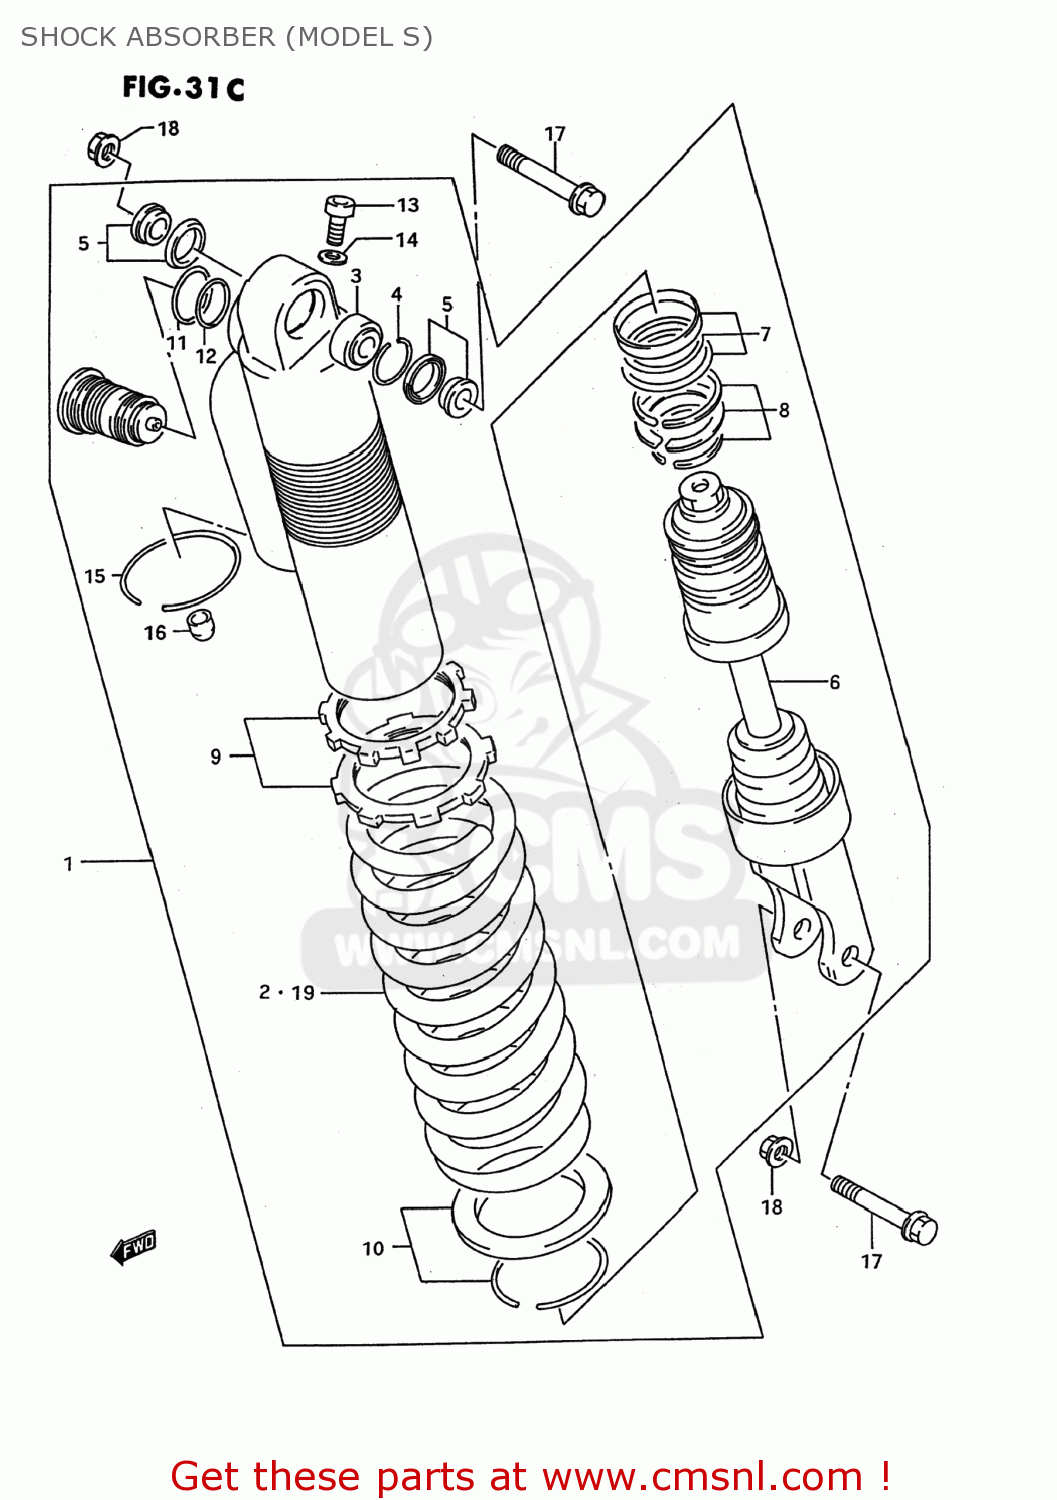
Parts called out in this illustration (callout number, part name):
1	ABSORBER ASSEMBLY,REAR SHOCK
2	SPRING
3	BEARING,RR CUSHION LEVER RR
4	RING,STOPPER
5	COLLAR SET,RR SHOCK ABSORBER
6	ROD,PISTON
7	O RINR SET
8	RING STOPPER SET,ABSORBER
9	ADJUSTER SET,SHOCK ABSORBER
10	SPRING SEAT SET,SHOCK ABSORBER
11	O RING
12	O RING,CTR BOLT UPR
13	BOLT,REAR SHOCK ABSORBER
14	GASKET,DRAIN,PLUG (NAS)
15	RING,STOPPER
16	CAP
17	BOLT,RR SHOCK ABSORBER
18	NUT
19	SPRING
